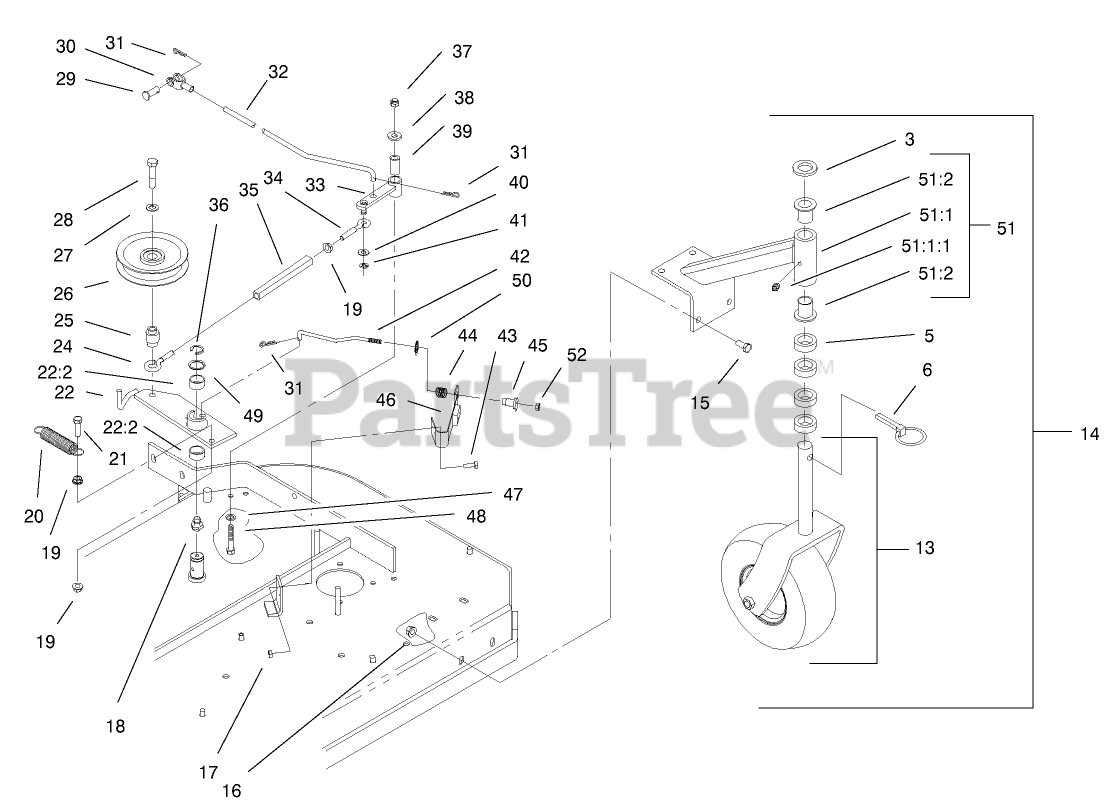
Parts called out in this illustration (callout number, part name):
2	FITTING-GREASE
3	WASHER-FLAT
5	SPACER-CASTER
10	SPACER
11	NUT-HH
12	WASHER-LOCK
13	CASTER/WHEEL ASM
14	CASTER/MOUNT ASM
15	SCREW-HH
16	NUT-HHF, WHIZ
17	NUT-LOCK, NI
18	FITTING-GREASE
19	NUT-HF
20	SPRING-EXTENSION
21	SCREW-HH
22	ENGAGE ARM ASM W/ BUSHINGS
22:2	SLEEVE-BEARING
24	EYEBOLT-THREAD, LH
25	BUSHING-ENGAGEMENT
26	PULLEY-IDLER
27	WASHER-BELLEVILLE
28	SCREW-HH
29	PIN-CLEVIS
30	YOKE-ADJUSTABLE
31	PIN-COTTER
32	ARM-ASSIST, LINKAGE
33	ARM-ASSIST
34	EYEBOLT-THREAD, RH
35	BODY-TURNBUCKLE
36	RING-RETAINING, EXT
37	NUT-LOCK, NI
38	WASHER-FLAT
39	TUBE-PIVOT
40	WASHER-PLAIN
41	RING-RETAINING, EXT
42	ROD-BRAKE
43	SCREW-HH
44	SPRING-COMPRESSION
45	SPACER-FLANGED
46	PAD AND SPRING ASM
47	WASHER-SPRING
48	SCREW-HH
49	WASHER-SPINDLE
50	RING-PUSH ON
51	SUPPORT ASM
51:1	SUPPORT-CASTER
51:1:1	FITTING-GREASE
51:2	BEARING-FLANGED
52	NUT-LOCK, NI
